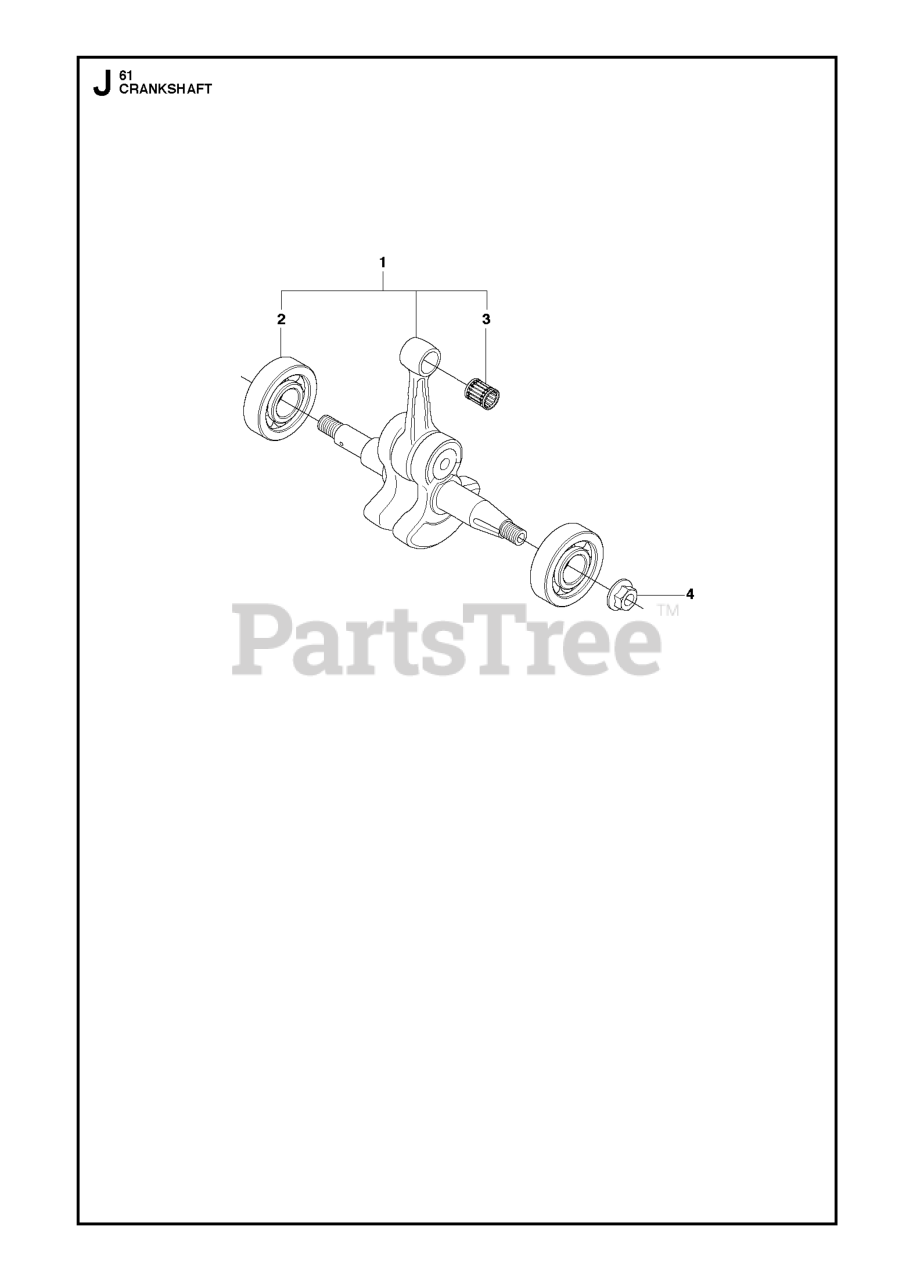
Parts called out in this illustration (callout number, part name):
1	CRANKSHAFT
2	BALL BEARING
3	NEEDLE BEARING PISTON PIN 12X1
4	NUT W/ WASHER
